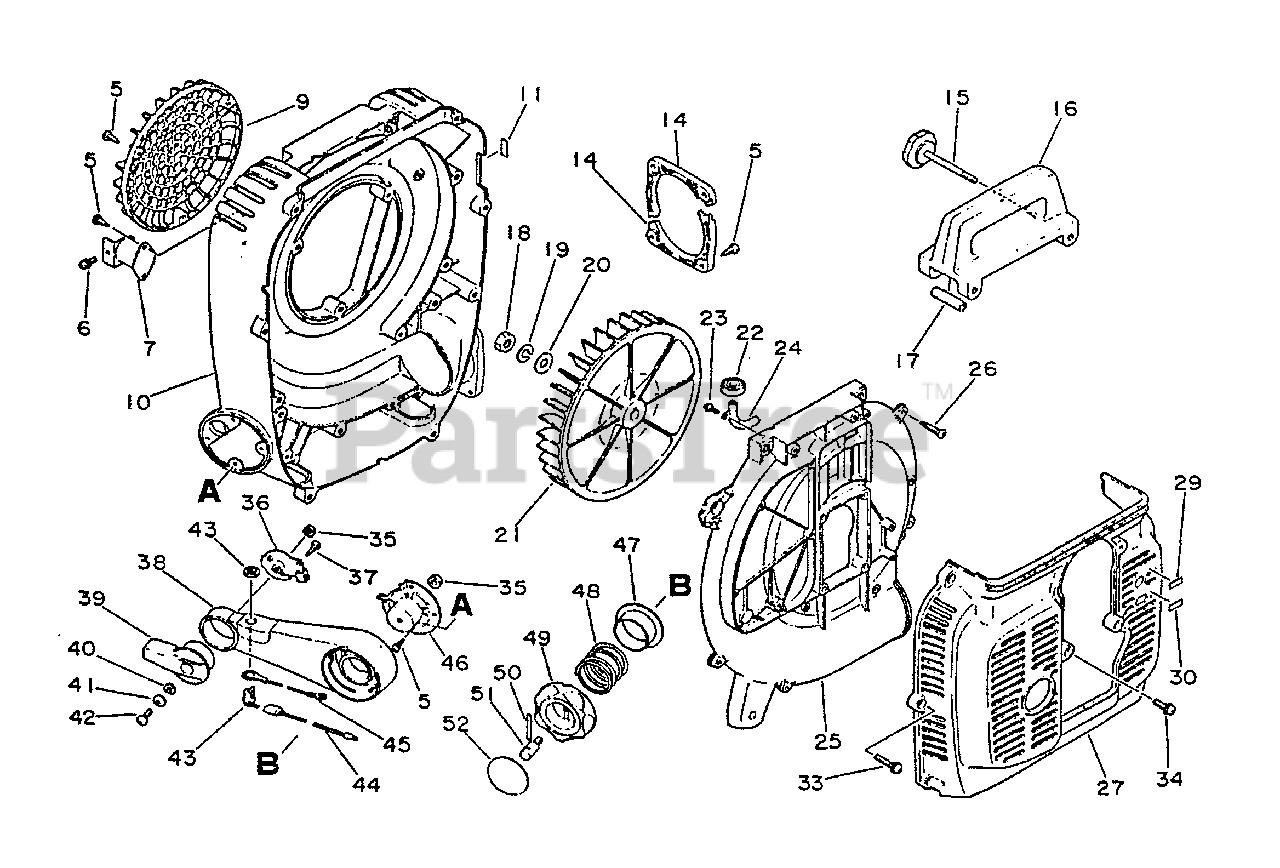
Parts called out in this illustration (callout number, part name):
5	SCREW 5×12
6	SCREW 5×12
9	SHIELD, DEBRIS
10	COVER, FAN - INNER
11	LABEL - CHOKE
14	BRACKET
15	BOLT
18	NUT 10 MM
19	WASHER, SPRING 10
20	WASHER 10.5×18×1.6
23	SCREW 4×10
24	PIPE, INTAKE
25	COVER, FAN - OUTER
26	SCREW 5×25
27	COVER, ENGINE
29	LABEL, CAUTION - IDLE
30	LABEL - CAUTION
33	SCREW 5×20
34	SCREW 5×15
35	NUT, HEX M6
36	BRACKET, THROTTLE
37	SCREW 4×10
38	MOUNT, THROTTLE LEVER
39	TRIGGER, THROTTLE
40	WASHER 6.5×13×1
41	WASHER
42	SCREW - 6×20
43	SWITCH, ON-OFF
45	LEAD - GROUND
46	PLATE
47	SEAT, SPRING
52	LABEL
